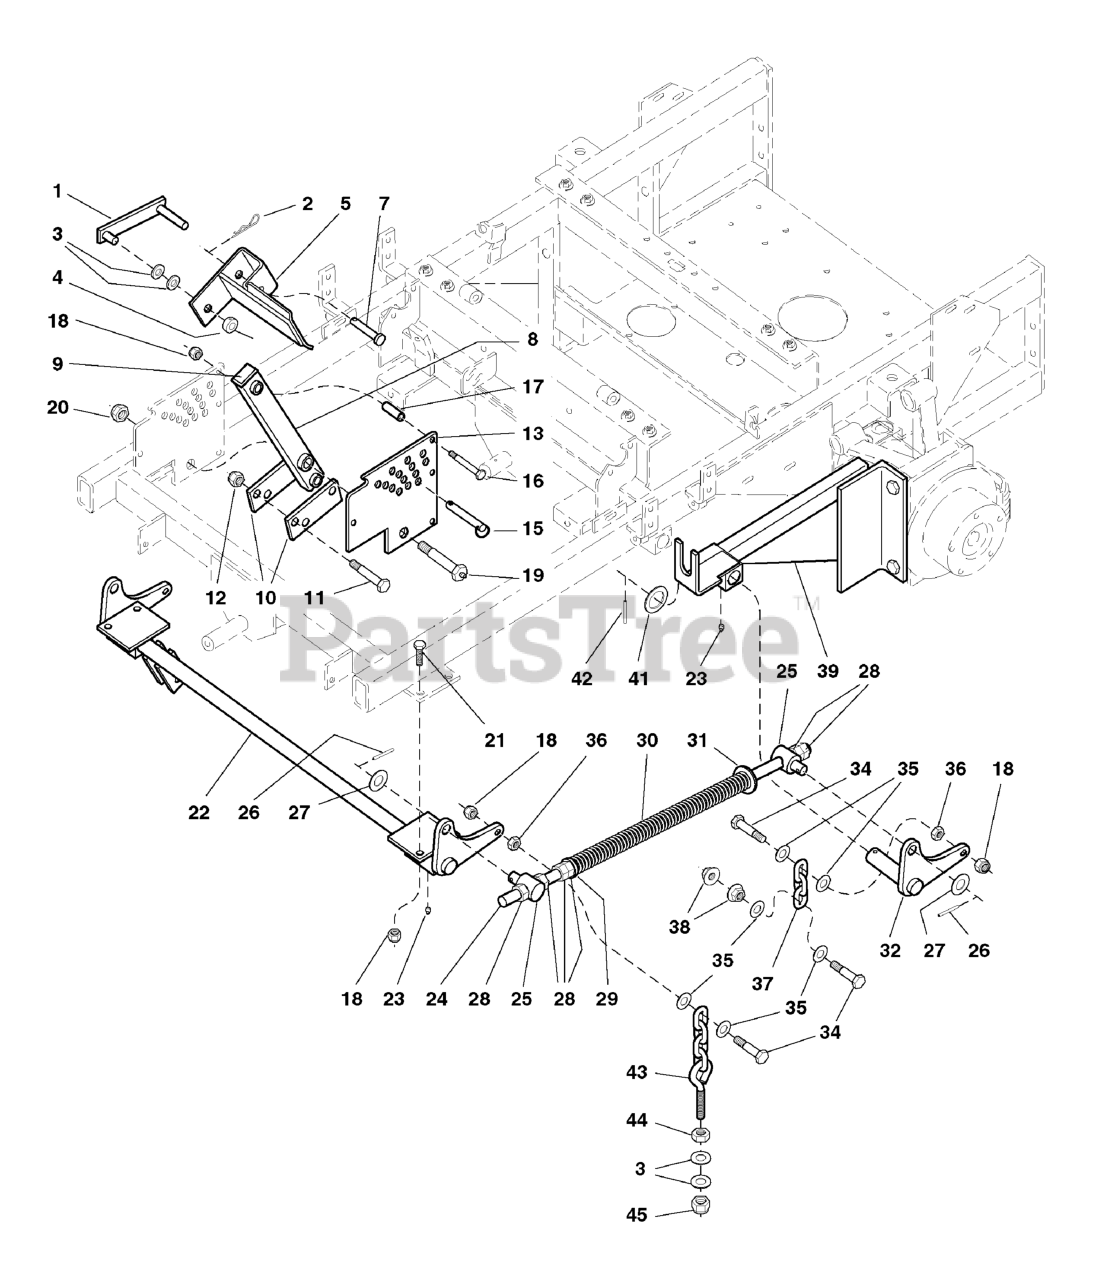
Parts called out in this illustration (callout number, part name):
1	DECK LIFT LOCK
2	HAIRPIN CLIP
3	WASHER, 1/2 SAE
4	COLLAR, 1/2" Set
5	WELD, DECK LIFT PEDAL
7	PIN, Clevis, 1/2 x 2-1/2
8	ARM, Deck Lift Pivot
10	DECK LIFT LINK
11	BOLT, 1/2-20 x 3
12	NUT, Hex, Nylon Lock, 1/2-20
13	DECK HEIGHT PLATE
15	PIN, 1/2 x 3
16	BOLT, 3/8-16 X 2-3/4" GD5 CZ
17	SPACER, .38 x .50 x 1.56
18	NUT, 3/8-16 HEX NYLON LOCK
19	LIFT PIVOT BOLT
20	NUT, 5/8-11 Hex Jam Nylon Lock
21	BOLT, 3/8-16 X 1-1/4" GD5 CZ
22	DECK LIFT SHAFT & MOUNT ASSEMBLY
23	GREASE FITTING
24	SPRING ROD
25	SPRING ROD PIVOT
26	PIN, Spring, 3/16 x 1-1/4
27	WASHER, 5/8" SAE
28	NUT, 5/8-11 Hex
29	SPACER, .63 x 1.06 x .23
30	SPRING, Deck Lift
31	WASHER, 5/8" USS
32	DECK LIFT PIVOT - LH
34	BOLT, 3/8-16 X 1-3/4" GD5 CZ
35	WASHER, 3/8 SAE
36	NUT, 3/8-16 HEX JAM
37	CHAIN, 3 LINKS
38	NUT, 3/8-16 Hex Serrated Flange
39	REAR DECK LIFT FRAME - LH
42	PIN, Roll, 3/16 x 1-1/2
43	HANGER, FRONT DECK - 4 LINK, 5.5" EB
44	NUT, 1/2-13 Hex
45	NUT, 1/2-13 HEX NYLON LOCK
